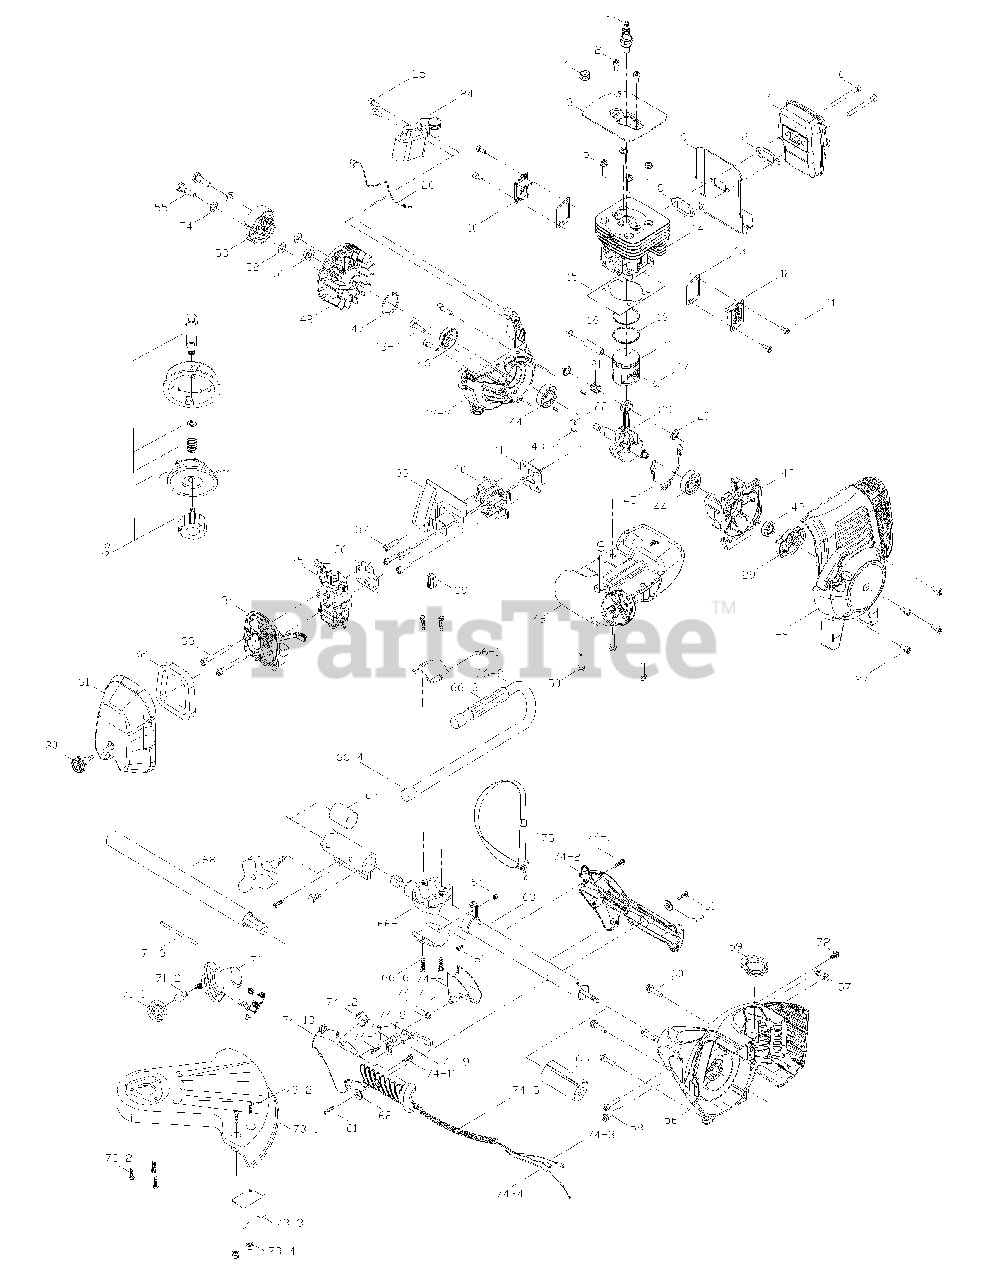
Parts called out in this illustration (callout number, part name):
1	SPARK PLUG
3	PLATE (SPARK SIDE)
7	MUFFLE ASS'Y
8	MUFFLE GASKET
9	MUFFLE PLATE
10	COVER (FLYWHEEL SIDE)
14	CYLINDER
16	PISTON RING
18	PISTON PIN
20	AXLS COVER
21	NEEDLE BEARING
23	CRANK/ROD ASS'Y
24	IGNITION COIL
26	COIL WIRE
28	STARTER HOUSING ASS'Y
29	PAWLS ASS'Y
30	KNOB
31	FILTER COVER
34	FILTER ASS'Y
35	CARBURETOR
36	CARBURETOR GASKET
40	INSULATOR
41	INSULATOR GASKET
43	CRANKCASE ASS'Y
43-1	CRANKCASE (STARTER SIDE)
43-3	CRANKCASE (FLYWHEEL SIDE)
47	C RING
49	FUEL TANK ASS'Y
51	NUT
53	CLUTCH (WITH SPRING)
54	WAVE PLATE
56	TRANSMISSION SUPPORT ASS'Y
63	BAG BEHIND
64	NUT
66	HANDLE ASS'Y
66-5	CENTERPLECE
66-6	PARTS BAG
68	HOUSING ASS'Y
69	STRINGHEAD ASS'Y
70	GEAR HOUSING ASS'Y
71	PACCESSORIES
71-2	SPLINE SLEEVE
73	GASS SHIELD ASS'Y
73-1	GASS SHIELD
73-3	KIT, KNIFE
74	HANDLE ASS'Y
74-2	HOUSING, HANDLE
74-3	WIRE ASS'Y, SWITCH
74-4	THROTTLE CABLE
74-8	LIBERATE SHAFT
74-10	LIBERATE CHUNK
74-13	HOUSING, HANDLE
